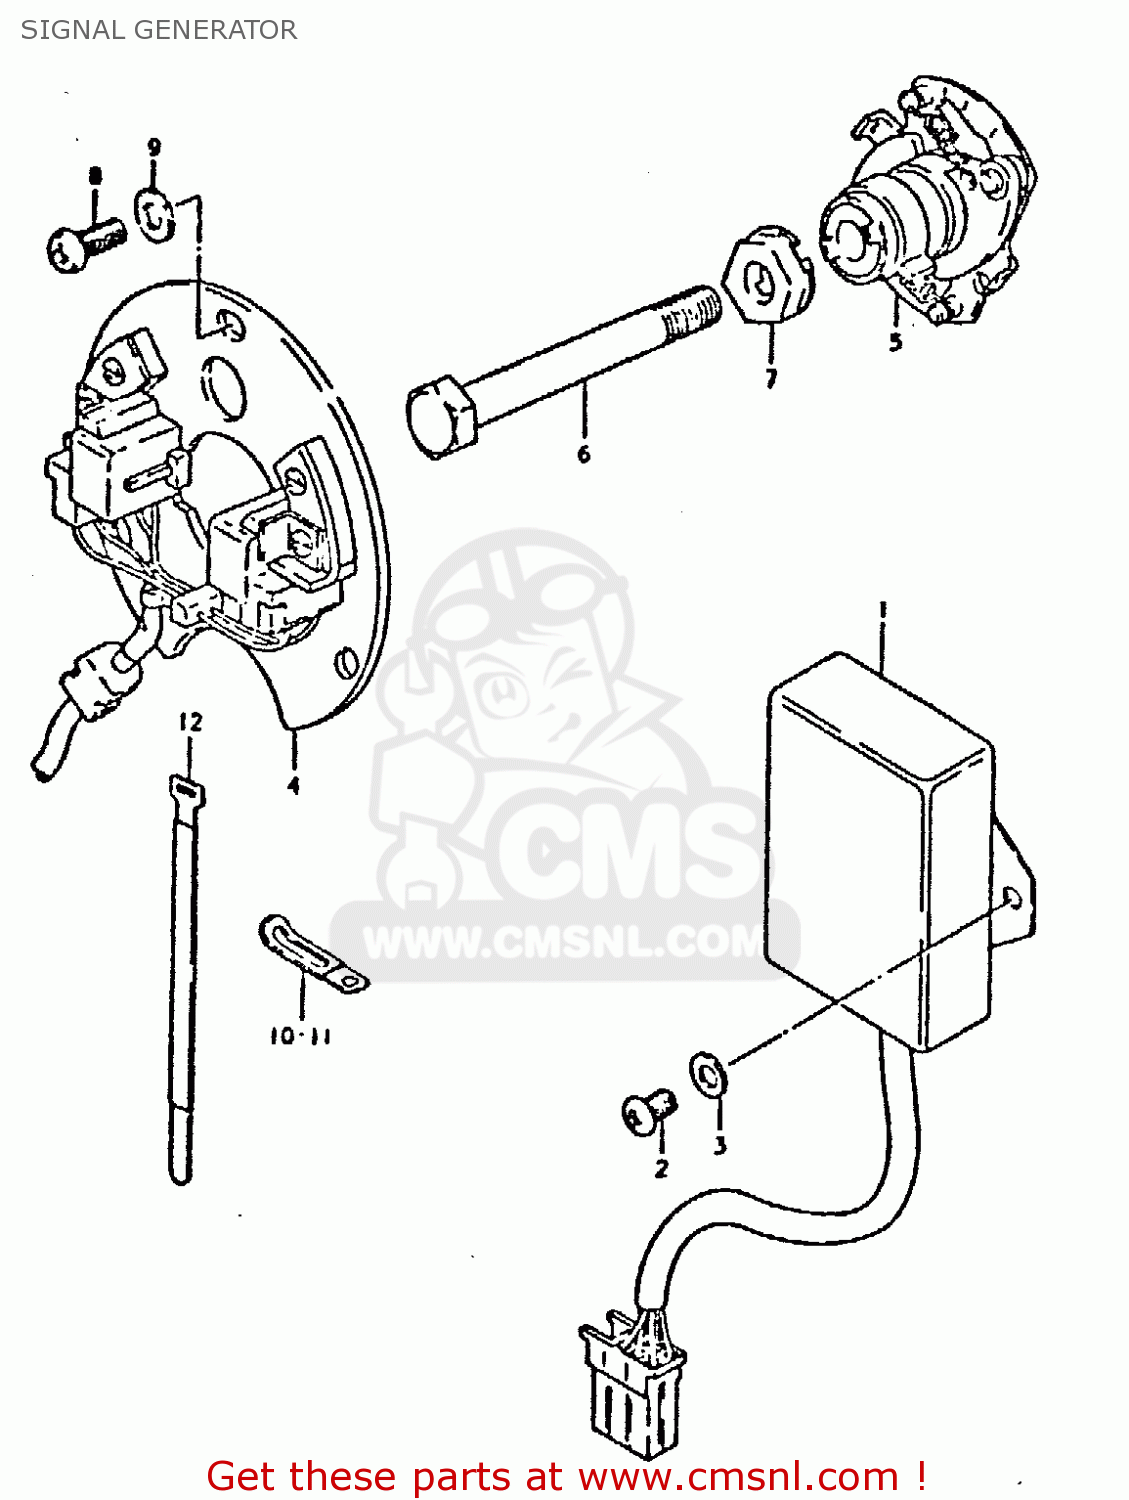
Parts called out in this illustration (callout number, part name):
1	IGNITER UNIT
2	SCREW
3	WASHER
4	SIGNAL GENERATOR ASSEMBLY
5	GOVERNOR ASSEMBLY
6	BOLT
7	WASHER
8	SCREW(5X12)
9	WASHER
10	CLAMP L:35
11	CLAMP
12	CLAMP
